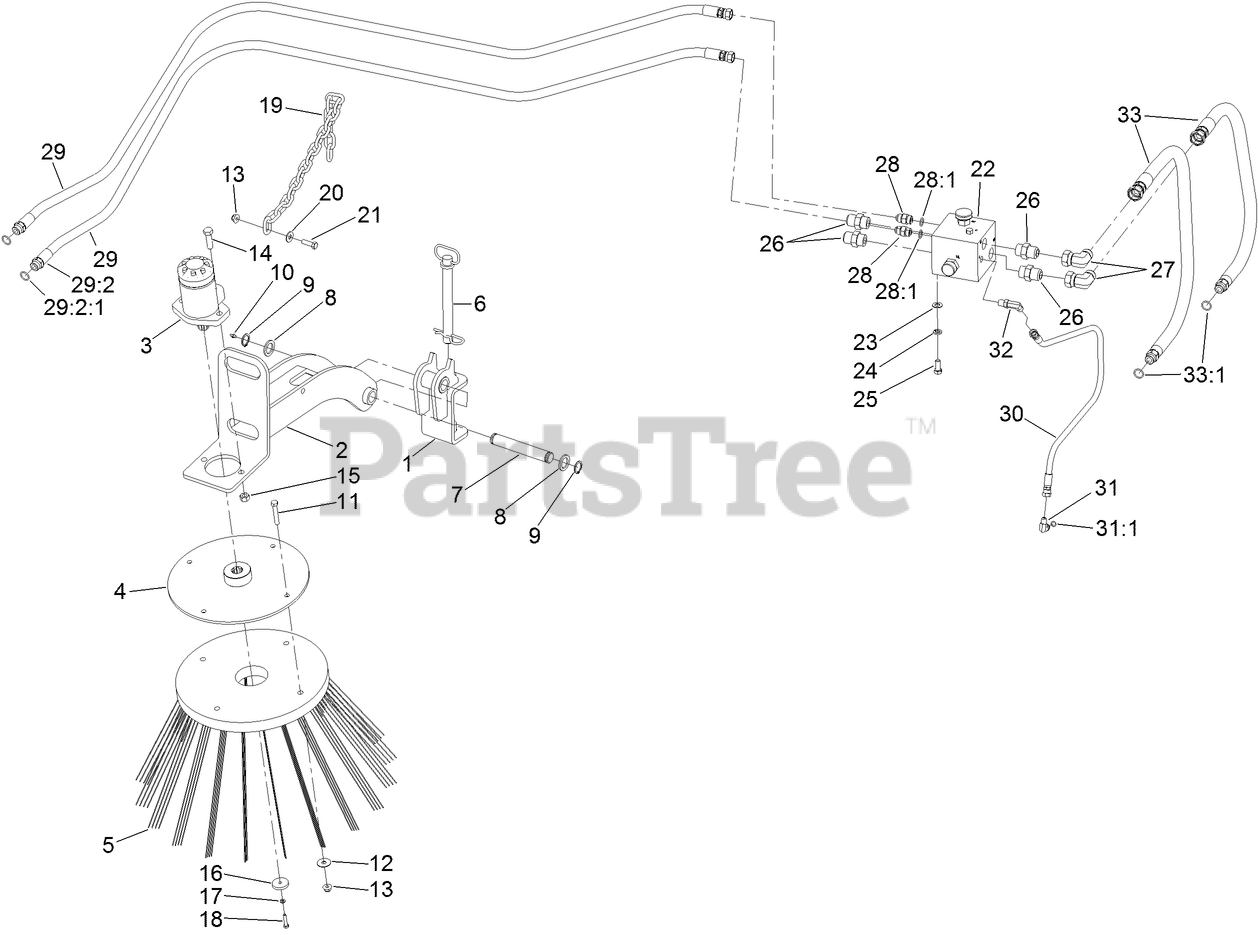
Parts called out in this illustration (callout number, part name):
1	PIVOT-BROOM, SIDE
2	MOUNT-BROOM, SIDE
3	MOTOR-BRUSH, SIDE
4	MOUNT-BRUSH, SIDE
5	BRUSH-SIDE
6	PIN-HITCH
7	PIN-HINGE
8	SPACER-HARDENED
9	RING-RETAINING
10	FITTING-ZERK
11	SCREW-HH
12	WASHER,FLAT,0.406IDX1.25OD,ST/ST 18
13	NUT-HF, NI
14	SCREW-HH
15	NUT-HH
16	WASHER-RETAINING
17	SCREW-HH
18	SCREW-HH
19	CHAIN-LIFT
20	WASHER-FLAT
21	SCREW-HH
22	MANIFOLD-BRUSH, SIDE
23	WASHER-FLAT
24	SCREW-HH
25	SCREW-HH
26	FITTING-STRAIGHT
27	FITTING-ELBOW, 90
28	FITTING-STRAIGHT
28:1	O-RING
29	HYD HOSE ASM
29:2	FITTING-STRAIGHT
29:2:1	O-RING
30	HOSE-HYD
31	ELBOW-90, ADJ
31:1	O-RING
32	FITTING-ELBOW
33	HYD HOSE ASM
33:1	O-RING
